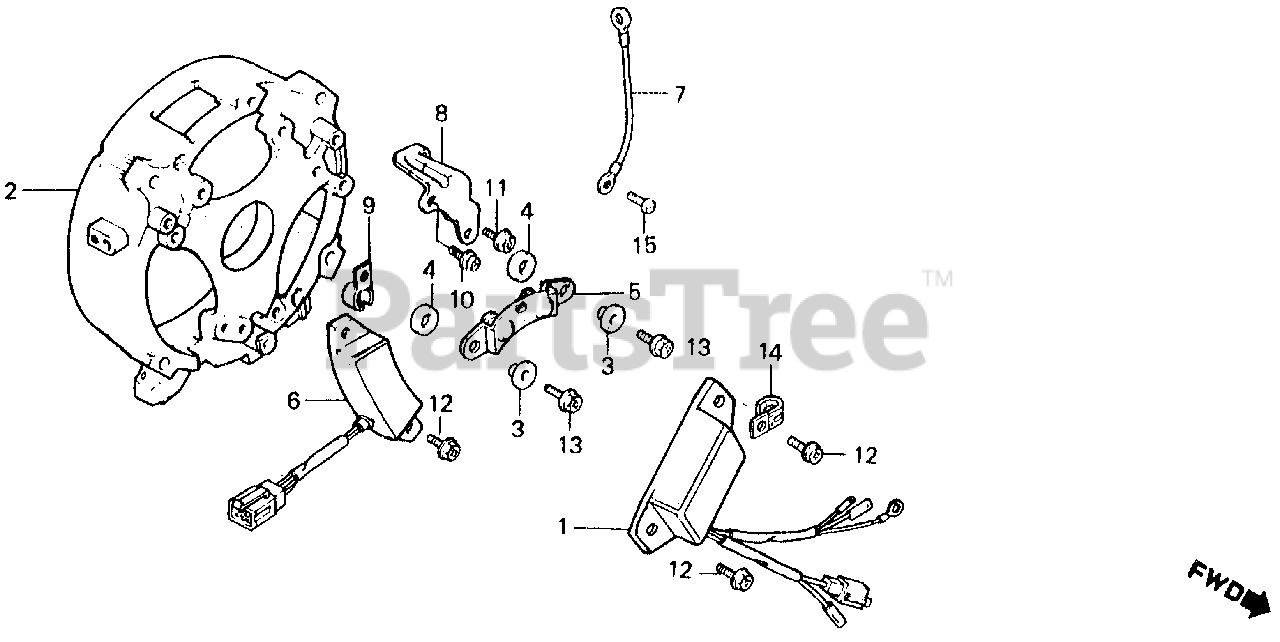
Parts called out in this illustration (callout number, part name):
1	MODULE, IGNITION CONTROL (CDI)
2	BRACKET, RR.
3	BUSH, INSULATING
4	WASHER, INSULATING
5	DIODE ASSY., D.C.
7	WIRE, GROUND
8	PLATE, CORD HOLDER
9	HOLDER, WIRE
11	SCREW, TAPPING (5X14)
12	SCREW, TAPPING (5X14)
13	SCREW, TAPPING (5X16)
14	CLIP B, WIRE
15	SCREW, PAN (5X8)
